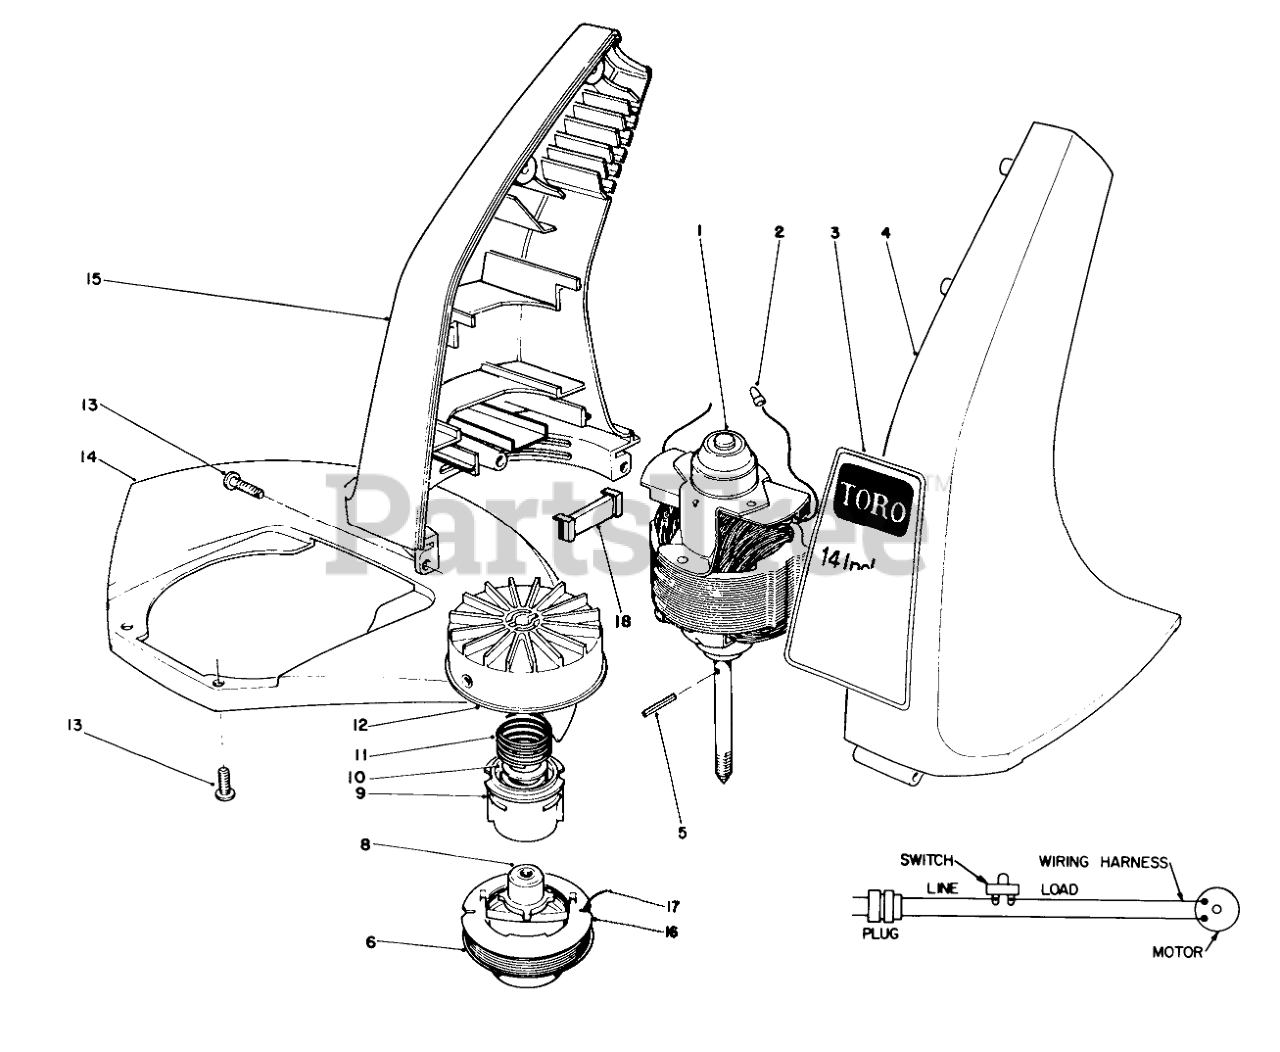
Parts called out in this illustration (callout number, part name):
1	Motor
2	CONNECTOR WIRE JOINT
3	DECAL, 14" TRIMMER
4	HOUSING,LH,12"/14"TRIMR
5	COIL PIN
6	Cutting Line (50 .065" Dia.)
8	DRIVER
9	SPOOL CORE
10	WASHER-FLAT
11	SPRING COMPRESSION
12	DRUM W/EYELET
13	Screw
14	SHIELD ASSEMBLY
15	HOUSING,RH,12"/14"TRIMR
16	SPOOL CAP
17	LINE-FILIMENT
18	INSERT - HOUSING
